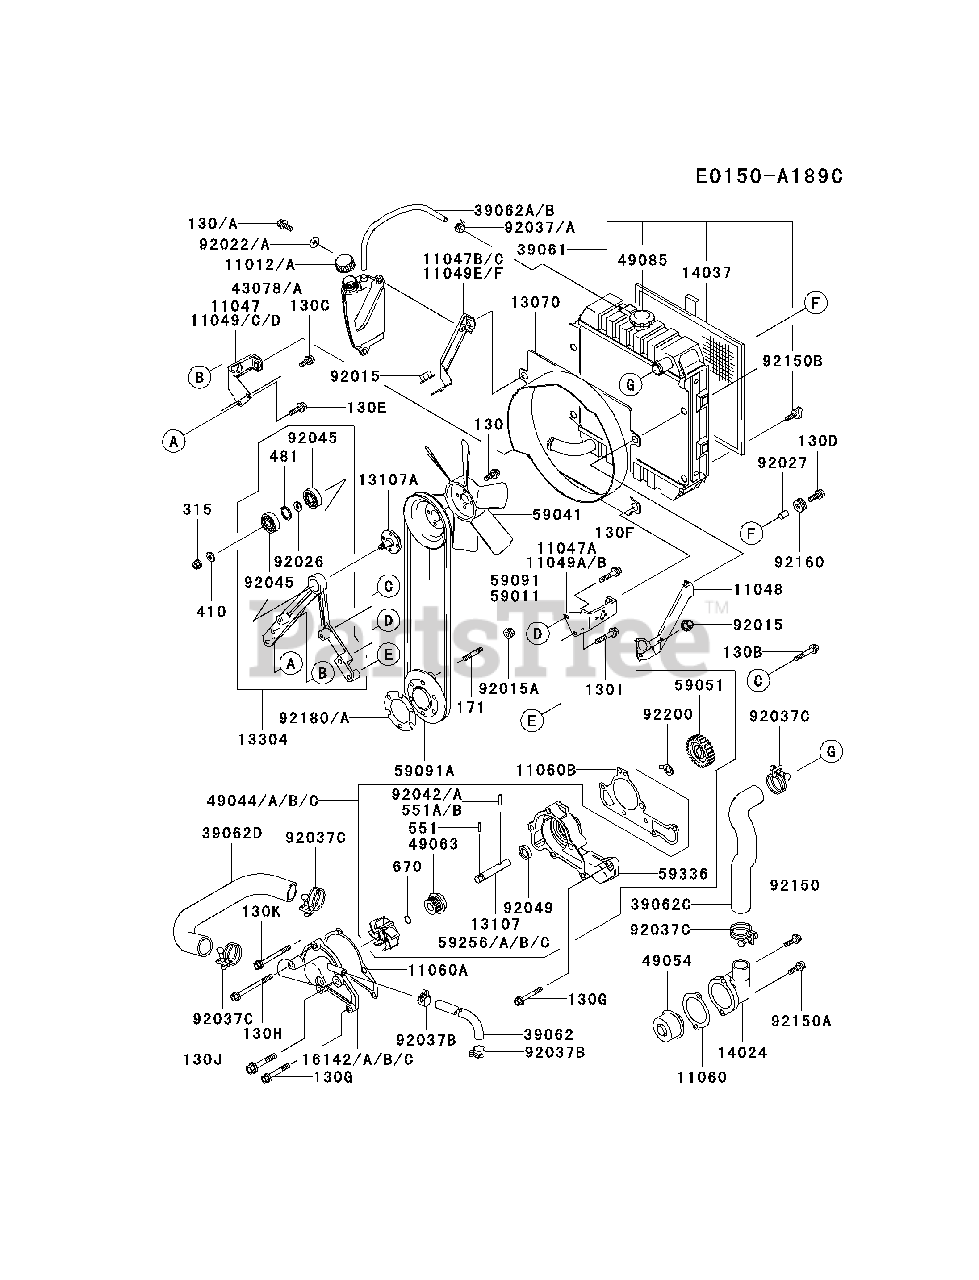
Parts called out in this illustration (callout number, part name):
130	BOLT-FLANGED
130B	BOLT-FLANGED
130C	BOLT-FLANGED
130D	BOLT-FLANGED
130E	BOLT-FLANGED
130F	BOLT-FLANGED
130G	BOLT-FLANGED
130H	BOLT-FLANGED
130I	BOLT-FLANGED
130J	BOLT-FLANGED
130K	BOLT-FLANGED
171	BOLT-STUD
315	NUT-HEX-FINE
410	W-PLAIN-S
481	CIRCLIP
551	PIN-DOWEL
670	O RING
92045	BEARING-BALL,6001DDUC3
92180	SHIM,T=0.6
92180A	SHIM,T=1.2
